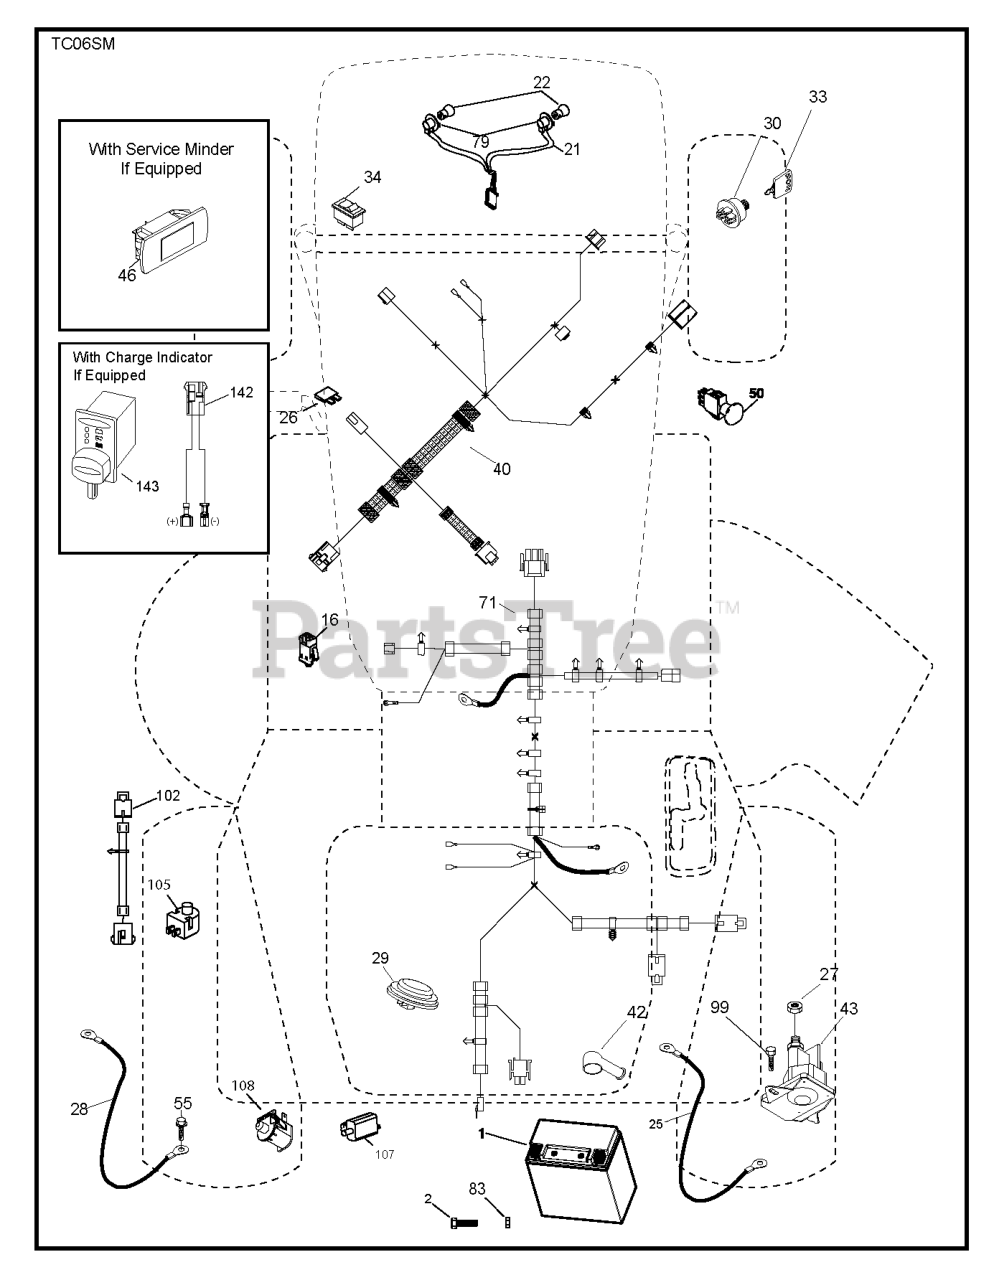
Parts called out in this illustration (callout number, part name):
1	BATTERY BATTERY 14AH 12V LEOC
2	SCREW.HEX.HEAD.CAP.M6 X1.12W
16	SWITCH INTERLOOK PUSH-IN
21	HARNESS.LIGHT W/4152J BULBS
25	CABLE.BATT.8GA.RED9.CRD2.5
26	FUSE 20AMP
27	NUT
28	CABLE.BATT.BLCK10.SLV.CRD2.5
29	SWITCH.SEAT.DELTA.OPC.
30	SWITCH.IGN.DELTA.W.LGH.ROS
33	KEY.CHAIN.BLISTER.PACK.GEN.USA
40	HARNESS.DASH.EL.SRD.CRD.RDY.ST
42	TERMINAL COVER
43	SOLENOID.STARTER.BRASS.PLUNGER
46	GUAGE.SRVCMNDR.HRMTR.
50	SWITCH.PTO.8TERMINAL.STD.BLK
55	SCREW 5/16"
71	HARNESS
79	BULB HOLDER ASM.
83	NUT NUT SQUARE
99	SCREW
102	HARNESS ASSY
105	REVERSE SWITCH
107	.WITCH.FULL BAGGER.INDICATOR
108	SWITCH.SNPMT.NCBT.CRD.MTL.BKPL
